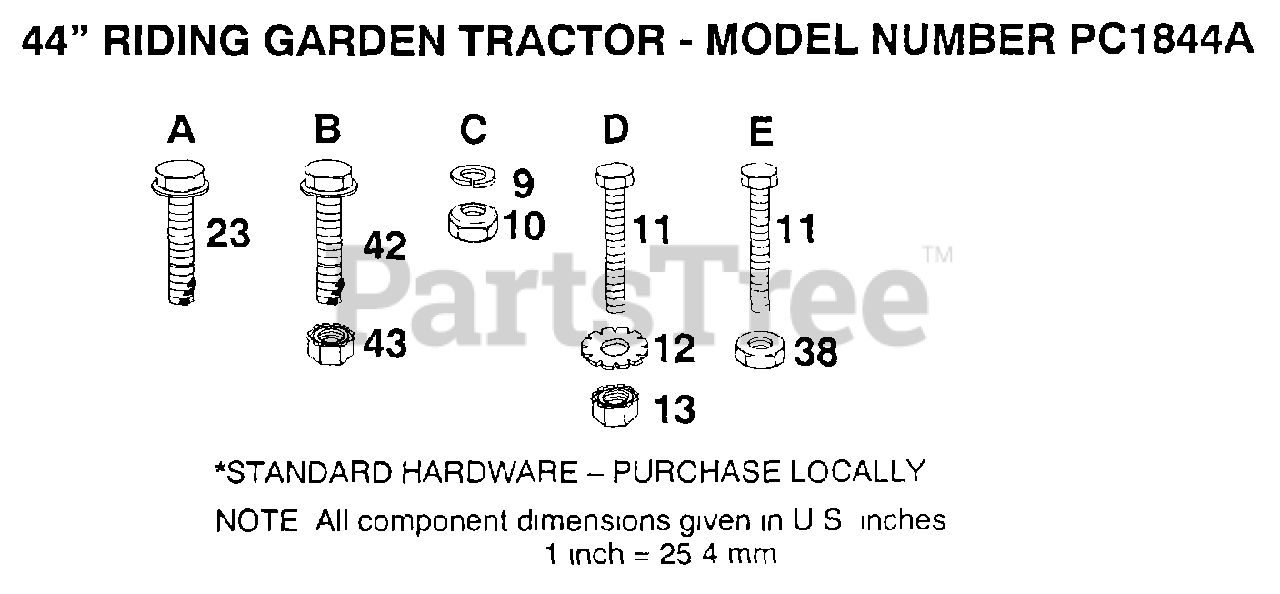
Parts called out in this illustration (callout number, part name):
10	NUT
11	BOLT
13	NUT
23	SCREW
42	SCREW
43	"NUT,KEPS"
